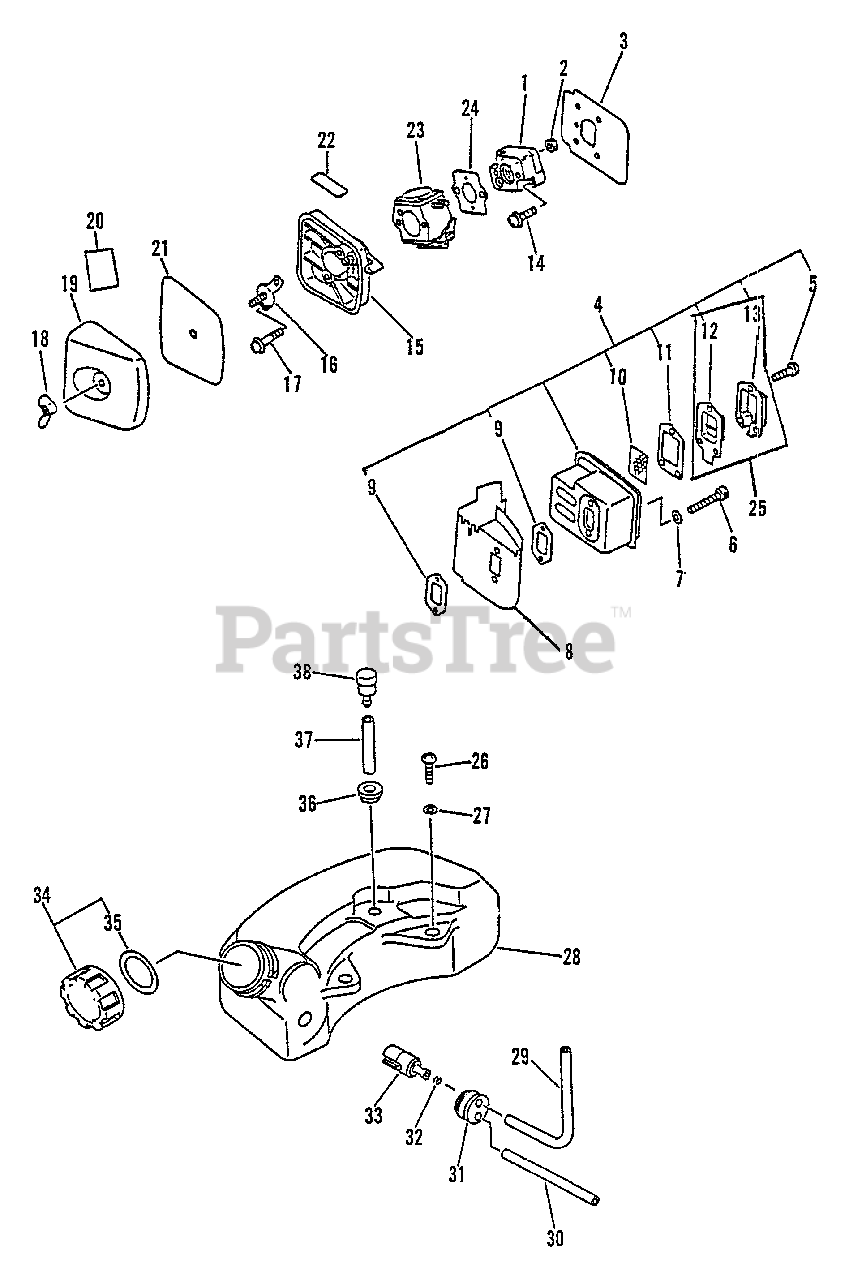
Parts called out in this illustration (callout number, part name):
1	INSULATOR, INTAKE
3	SHIELD, INTAKE
4	MUFFLER ASSY
5	SCREW - 4X10
6	SCREW - 5X55
7	WASHER - 5
8	COVER, EXHAUST
9	GASKET, EXHAUST
10	SCREEN, SPARK ARRESTOR
11	GASKET, EXHAUST
12	GASKET, EXHAUST - INNER
13	GUIDE, EXHAUST - OUTER
14	SCREW - 5X20
15	AIR FILTER CASE ASSY
16	PLATE, PREVENT
17	SCREW - 5X64
18	WINGNUT - 6
19	COVER, AIR FILTER
20	LABEL - TOP
21	FILTER, AIR
22	LABEL - CHOKE
23	CARBURETOR C1U-K18
24	GASKET, INTAKE
25	GUIDE, EXHAUST - OUTER
26	SCREW - 5X16
27	WASHER - 5
28	TANK, FUEL
29	PIPE - 3X5X180 -- BLACK
30	PIPE - 3X6X110 -- CLEAR
31	GROMMET
32	CLIP - 6
33	FILTER, FUEL
34	CAP ASSY
35	GASKET, CAP
36	GROMMET
37	PIPE - 3X6X35 -- BLACK
38	VENT, FUEL TANK
